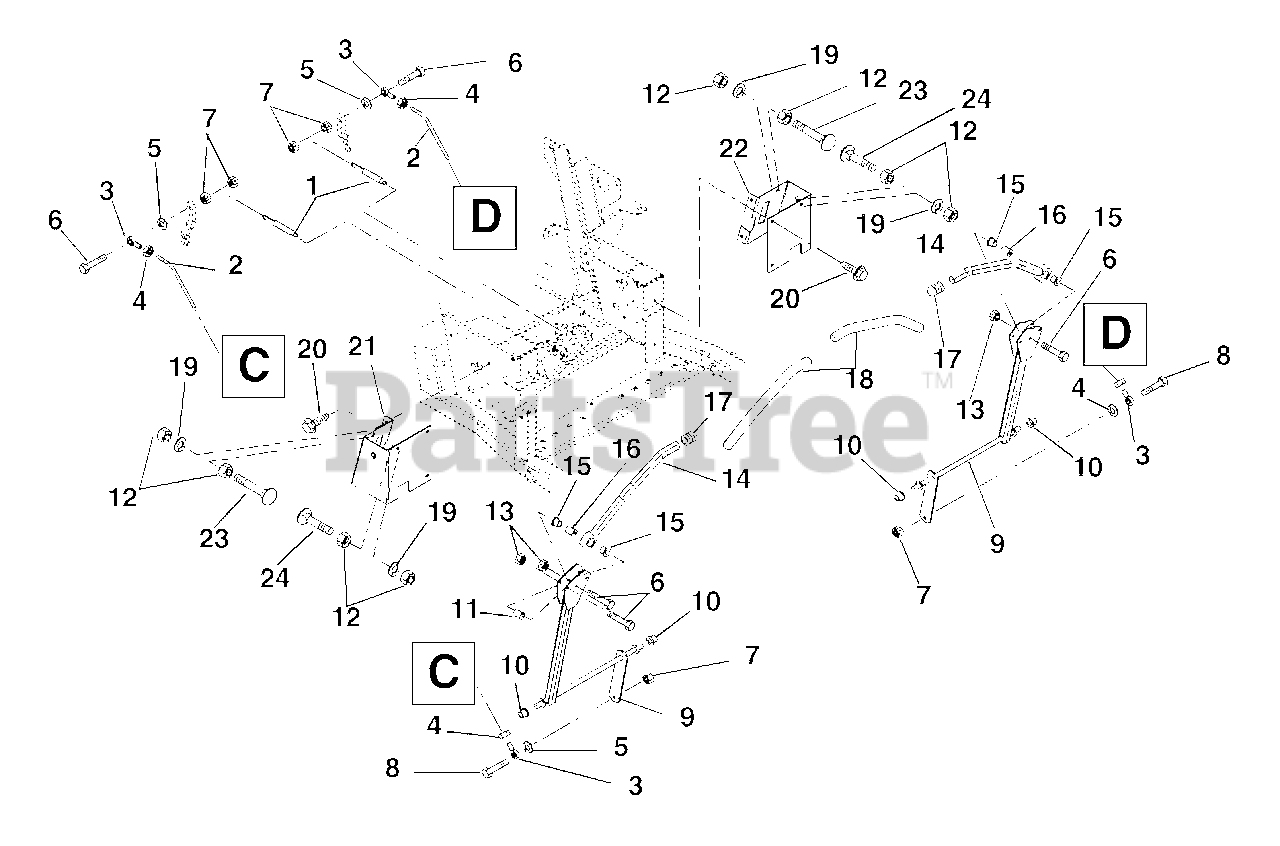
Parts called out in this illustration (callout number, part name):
1	Spring-Tension .062 x .56 x 8.0
2	Rod-Steering Adjustment
3	Rod End .312 Right-Hand-Female
4	Nut-Jam .31-24
5	Washer-Locking .31 x .078
6	Bolt-Hex .31-18 x 1.75 Grade 5
7	Nut-Locking-Center .31-18
8	Bolt-Hex .31-18 x 1.50 Grade 5
9	Rod-Steering
10	Bushing-Flange .515 x .750 x .745 x 1.00
11	Eccentric
12	Nut-Hex .38-16
13	Nut-Locking-Center .31-18
14	Handle Weldment Left-Hand
14	Handle Weldment Right-Hand
15	Bushing-Flange-Nylon .762 x 1.48 x .44
17	Caplug- Handlebar
18	Grip-Handlebar
19	Washer-Locking .38 x .094
20	Screw-Tapping .38-16 x .75 Hex Washer Head
21	Mount-Steering Rod-Right Hand
22	Mount-Steering Rod-Left Hand
23	Bolt-Round Head Square Neck .38-16 x 2.00
24	Bolt-Round Head Square Neck .38-16 x 1.50
